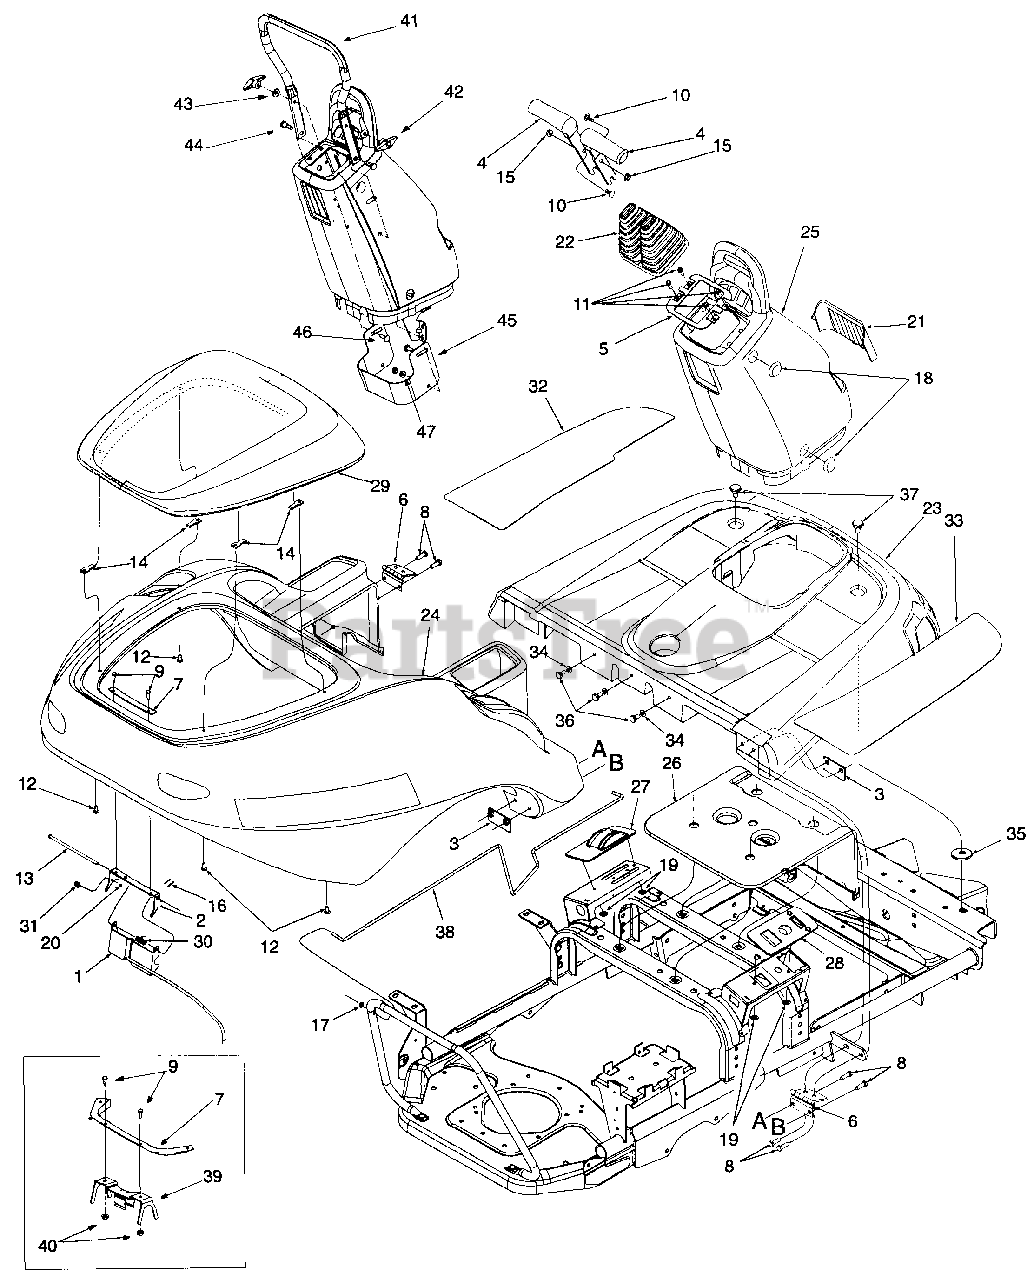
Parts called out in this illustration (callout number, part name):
1	Handle Ass'y, Latch
2	Bracket, Latch
3	Plate Ass'y, Body Mounting
4	Handle, Control
7	Plate, Latch Mounting
8	Screw, Hex Cap, 5/16-18 x 1.0 GR5
9	Screw, Pan Hd, #10-24 x .625
10	Bolt, Carriage, 5/16-18 x .75
11	Screw, Hex Wash Hd. Tap 1/4-20 x .75
12	Screw, Truss Machine 1/4-20 x .625 GR2
13	Rod, Latch Mounting
14	Nut, U-Type Speed, 1/4-20
15	Nut, Hex Flange Lock, 5/16-18 GR5
16	Pin, Cotter, 1/16 x .75
17	Push Cap, 1/4
18	Plug, Button
19	Push Nut
20	Rivet, Pop, .125 Dia
21	Lens, Headlight
22	Bellow, Control
23	Body, Front Floor
24	Body, Rear Engine Compartment
26	Cover, Seat Base
27	Cover, LH Control Panel
28	Cover, RH Control Panel
29	Cover, Engine
30	Spring, Torsion
31	Clip, Spring
32	Pad, Floor LH
33	Pad, Floor RH
34	Washer, Flat
35	Washer, Flat, .406 x 1.5 x .110
36	Bolt, Shoulder
37	Bolt, Shoulder, .75 x .245:3/8-16
38	Rod, Prop Support
39	Clip Spring Bracket Assembly
40	Hex Nut Lock Flange 1/4-20
43	Bell Wash .340 ID
44	Shoulder Screw .437 Dia .54
47	Nut Hex Flange Lock 5/16-18 GR5
